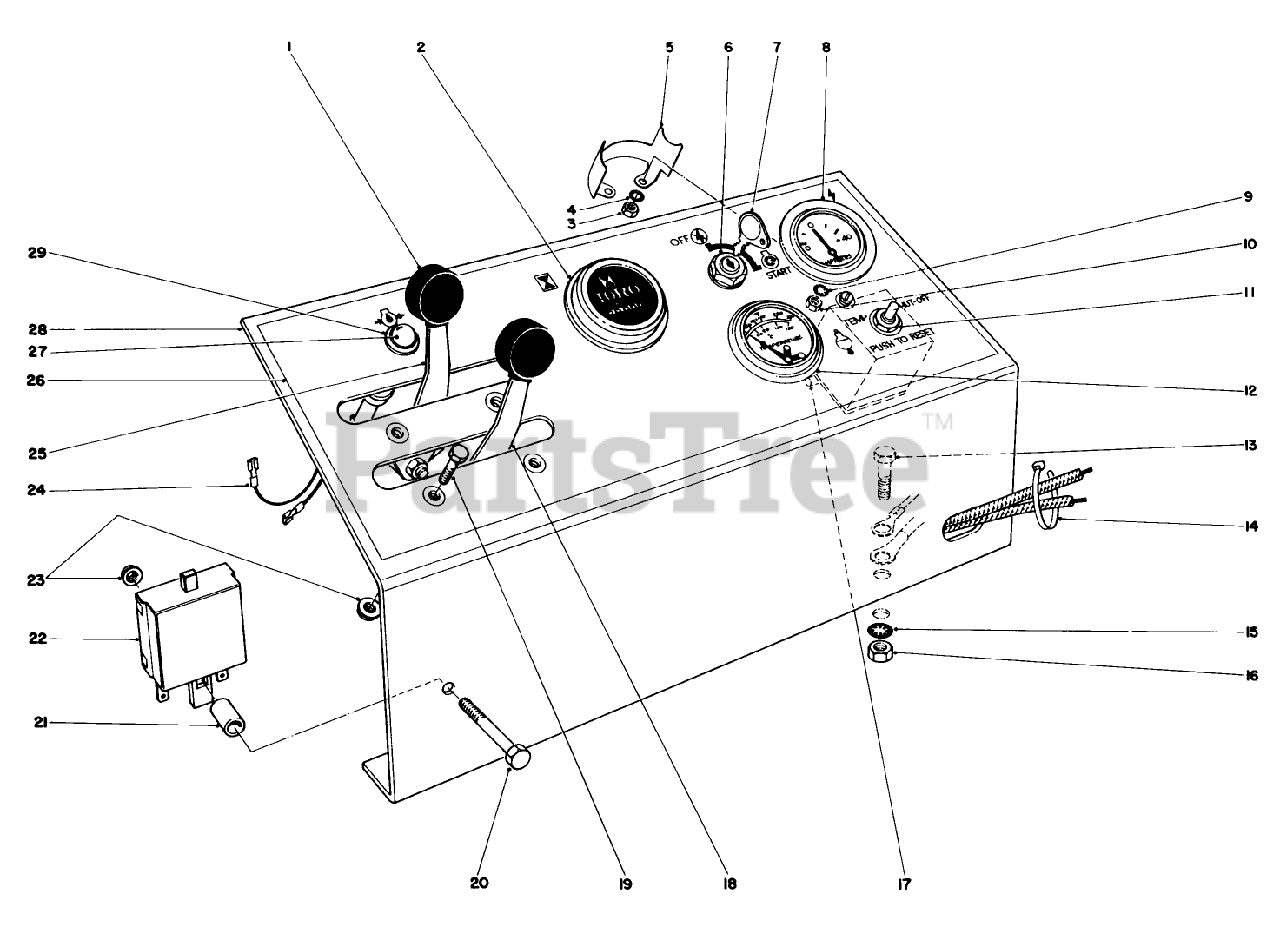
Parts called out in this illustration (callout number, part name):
2	Hour Meter
3	Nut
4	Lockwasher
5	MTNG BRKT W/38-1660
6	SWITCH
7	KEY-IGNITION
8	AMMETER GAGE
9	WASHER-LOCK, INTERNAL
10	NUT-HEX
11	TEMP RESET RELAY
12	ENG TEMP SWITCH GAGE
13	SCREW-HH
14	TIE-CABLE
15	WASHER-LOCK, INTERNAL
16	NUT-HEX
17	Fuse Temp Relay 14 AMP SFE
18	Throttle Control (Incl. Ref. #1)
20	SCREW-HH
21	SPACER
22	BUZZER ASM
23	NUT-LOCK, FLANGE
24	LEAD WIRE ASM
25	Choke Control (Incl. Ref. #1)
26	Decal-Instrument Panel
28	INST PANEL B
29	Warning Light (Incl. Ref. #27)
